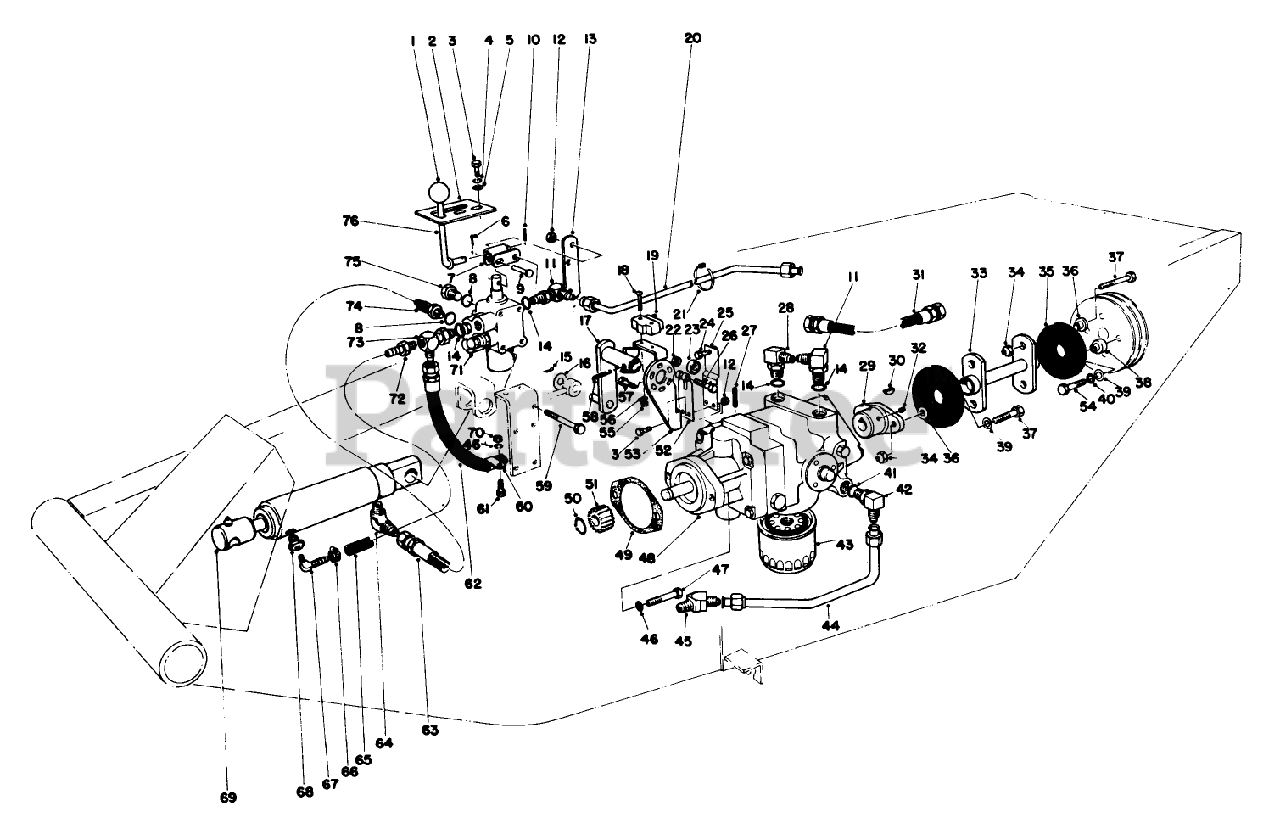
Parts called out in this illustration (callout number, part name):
2	LATCH-LEVER, VALVE
3	SCREW-HH
4	WASHER-LOCK
5	WASHER-FLAT
6	PIN-COTTER
7	Link-Valve Lever
8	O-RING
9	PIN-CLEVIS
10	PIN-ROLL
11	FITTING-ELBOW, 90 DEG
12	NUT-LOCK, NI
13	LEVER-VALVE, PIVOT MOUNT
14	O-RING
15	PIN-COTTER
16	WASHER-FLAT
17	Lever-Pump
18	SCREW-MACHINE
19	Micro Switch
20	PRESSURE LINE TUBE
21	TIE-CABLE
22	NUT-LOCK, NI
23	BEARING-BALL
24	SCREW-HH
25	EXTENDED LEAF SPRING ASM
26	SCREW-HH
27	PIN-ROLL, SLOTTED
28	FITTING-HYD, 90 DEG
29	HUB-PUMP
30	KEY-WOODRUFF
31	PUMP-COOLER HOSE
32	SCREW-SET, HSH
33	Drive Coupling
34	NUT-LOCK, CONE
35	Coupling Rubber
36	SPACER-COUPLING
37	SCREW-HH
38	SPACER-COUPLING, RUBBER
39	WASHER-FLAT
40	WASHER-LOCK
41	O-RING
42	FITTING-ELBOW, 90 DEG
43	FILTER-OIL, TRANSMISSION
44	AXLE-PUMP TUBE ASM
45	45 DEG FITTING
46	WASHER-LOCK
47	SCREW-HH
48	Transmission Inline (Incl. Ref. #30 & 51)
49	Gasket
50	Ring-Snap
51	Gear
52	SPRING-LEAF
53	Plate-Pump
54	SCREW-HH
55	NUT-HEX
56	Lockwasher
57	1/4-20 X 3/4 THDG SCR
58	PIN-SPRING
59	SCREW-HH
60	CLAMP-R
61	SCREW-HH
63	VALVE-CYLINDER HOSE
64	ELBOW
65	GAS LINE
66	CLAMP-HOSE
67	CONNECTOR-HOSE
68	REDUCING BSGH
69	Hydraulic Cylinder
70	NUT-HEX
71	Valve
72	FITTING-STRAIGHT
73	FITTING ASM
74	FITTING-ELBOW, 90
76	Lever Valve
